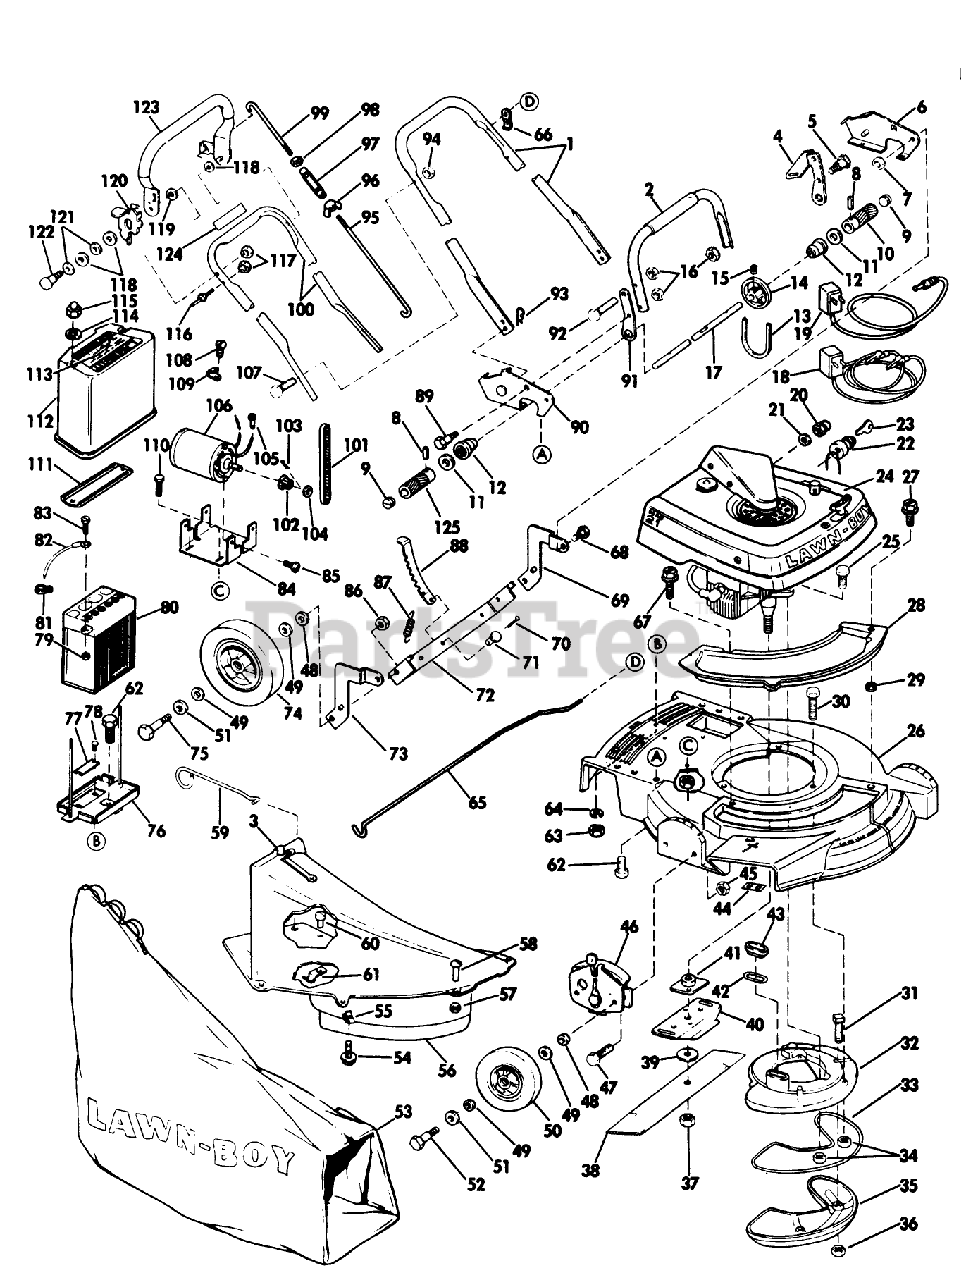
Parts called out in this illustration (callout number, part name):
7	NUT
8	PIN
9	GREASE PLUG
10	LEFT ROLLER
19	BATTERY CHARGER
27	SCREW SEMS TRM HEX HD
30	SCREW
34	NUT
36	LOCKNUT E
37	NUT-BLADE
39	WASHER
41	PLATE AND COLLAR ASM
42	GASKET S
43	SLEEVE
45	NUT
48	WASHER WROUGHT
49	WASHER
51	SPACER
52	BOLT WHEEL
53	89802 LB WHOLE GOODS
54	SCREW
55	SPEED NUT ARDEN
56	Skirt Assembly
57	NUT S
64	Washer
65	ROD & CLIP
68	BOLT-SHOULDER
75	BOLT
81	RETAINER ARDEN
83	SCREW F
86	LOCKNUT
87	SPRING N.A.S
89	BOLT PIONEER
92	SCREW
93	HAIR PIN
107	SCREW
108	SCREW S
110	SCREW S
114	Washer
115	PALNUT S
118	WASHER M
122	BOLT PIONEER
